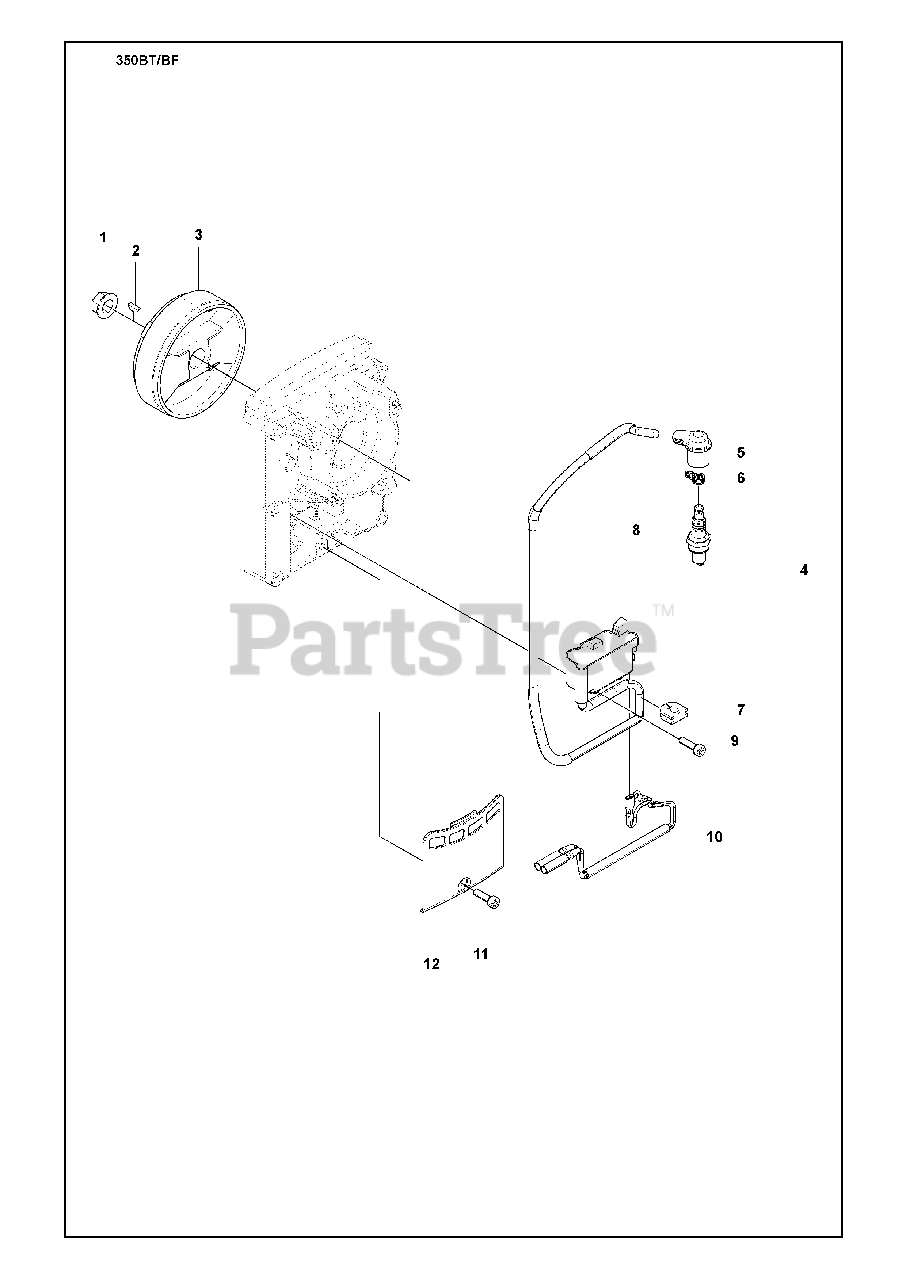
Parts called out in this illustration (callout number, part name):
1	NUT
2	KEY
3	FLYWHEEL
4	IGNITION COIL
5	CAP
6	SPRING
8	SPARKPLUG NGK CMR7H
9	BOLT
10	CORD-C
11	BOLT
